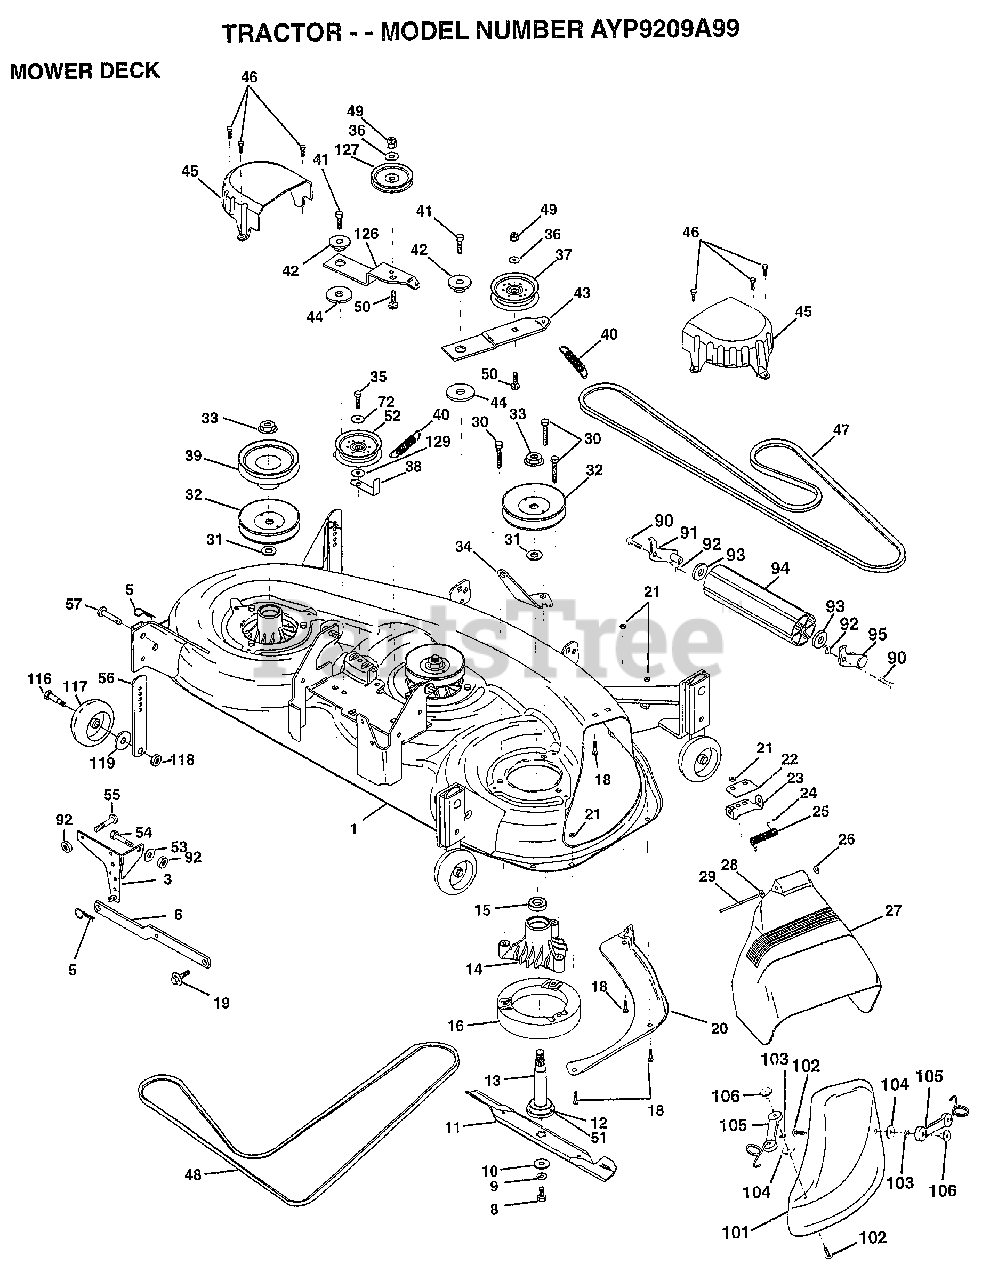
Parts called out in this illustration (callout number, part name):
1	DECK.WELDMENT.MOWER
3	BRKT.ASM.SW.44/50
8	BLADE BOLT
10	WASHER.HARD.BLADE
11	"BLADE MULCH 46"""
12	BEARING.BALL
13	SHAFT.ASM.W/BRNG
14	HOUSING.MAND.44.V
15	BEARING
16	STRIPPER RND MWR
18	BOLT
19	BOLT SHD 5/16-18
19	WASHER
20	BAFFFLE.VORTEX.46
22	STIFFENER BRKT
23	DEFLECTOR BRKT
24	CAP-SLEEVE LT
26	NUT PUSH M
27	SHIELD DEFLECTOR
28	WASHER
29	HINGE ROD
30	"SCREW-THD ROLL,WA"
31	WASHER
32	PULLEY.MAND.36/46
34	ANCHOR.SPRING.46
35	SCREW LT
36	WASHER
37	FLAT IDLER PULLEY
38	"KEEPER BELT,IDLER"
39	PULLEY.DRV.DCK.46
40	"SPRING.SEC.44""VEN"
41	SCREW
42	SPACER RETAINER
43	ARM.IDLER.DECK.46
44	HARDENED WASHER
45	COVER.MANDREL.46
46	SCREW.1/4-20X5/8
47	BELT-V.SEC.46.KEL
48	BELT.MWR.PRM.85.4
50	BOLT.3/8-16X1.50
51	WASHER.FELT.
52	"PULLEY IDLER,FLAT"
53	WASHER
54	BOLT
57	RIVET-PAN HEAD
72	WASHER HYT
90	BOLT
92	NUT
93	WASHER
101	COVER.MULCHING.
102	SCREW
103	LOCKWASHER
104	WASHER #10
105	LATCH ASSY.BAGGER
106	WELDNUT
116	BOLT.SHOULDER
117	WHEEL GAGE DONUT
118	LOCKNUT
126	ARM.IDLER.PRIM.46
127	PULLEY.IDLER.4.25
